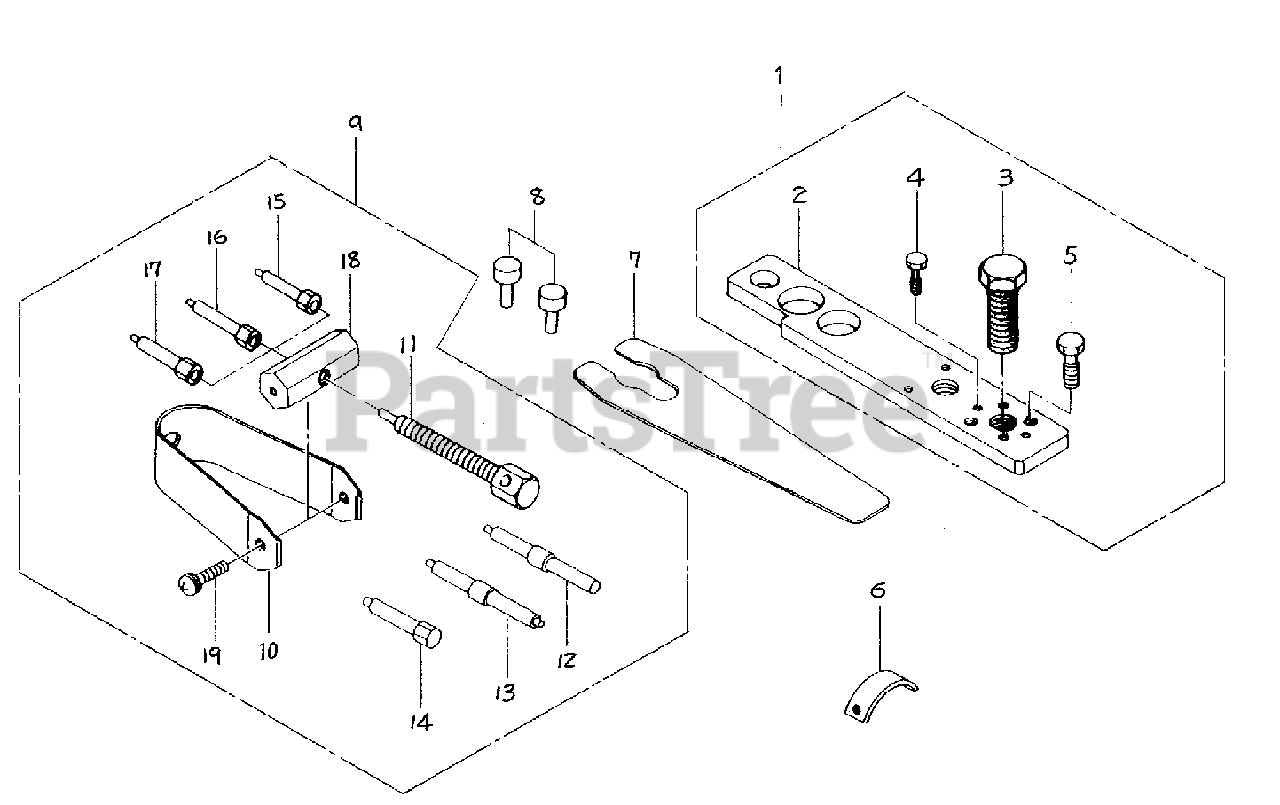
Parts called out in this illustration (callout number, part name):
1	PULLER ASSY
2	LEVER
3	BOLT, CENTER
4	BOLT
5	BOLT
6	GAUGE, GAP
7	SPANNER WRENCH, FLYWHEEL
8	STOPPER
9	PULLER ASSY
11	BOLT
12	PING, GUIDE
13	PING, GUIDE
14	PING, GUIDE
15	PIN, ADAPTOR
16	PIN, ADAPTOR
17	PIN, ADAPTOR
18	BOSS
